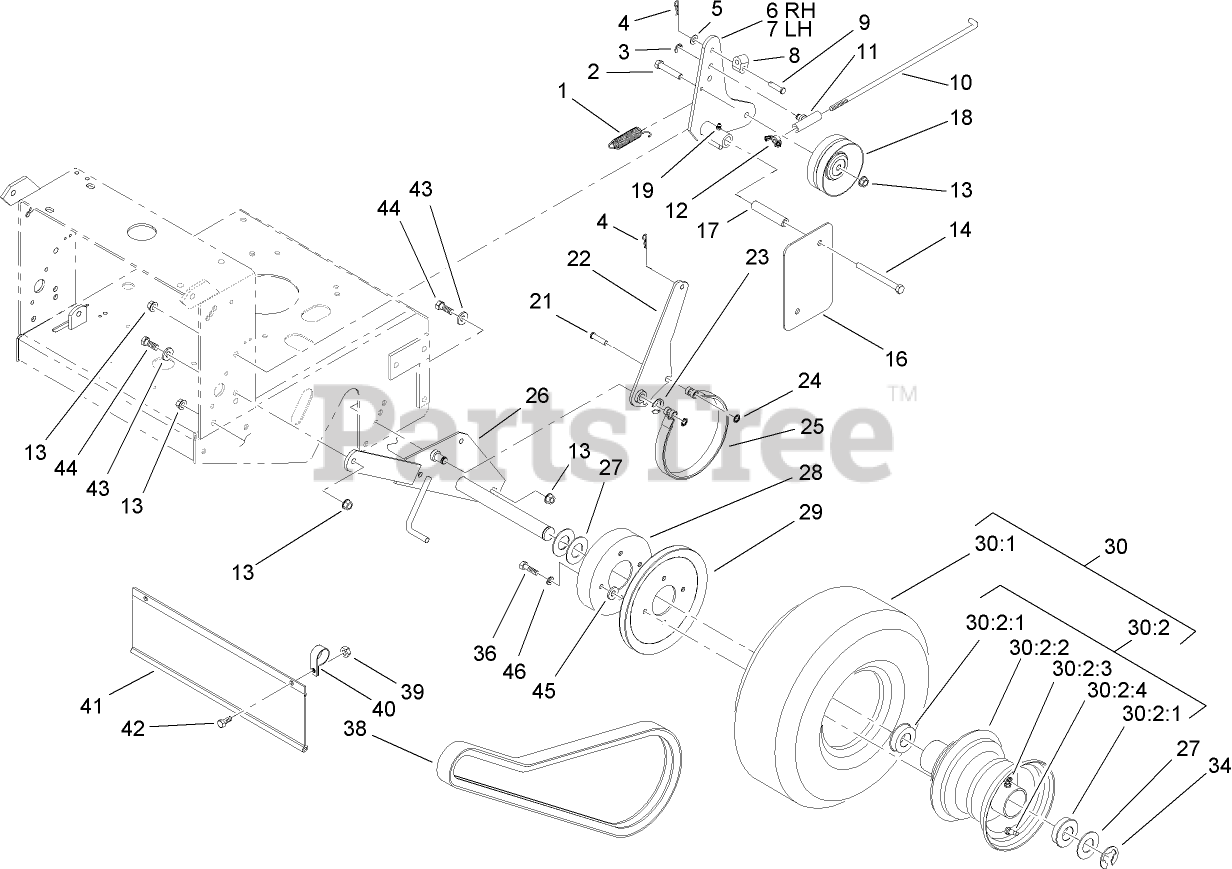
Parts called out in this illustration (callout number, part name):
1	SPRING-EXTENSION
2	SCREW-HH
3	RING-RETAINING
4	PIN-COTTER
5	WASHER-PLAIN
6	ARM-IDLER, RH
7	ARM-IDLER, LH
8	FITTING-ROD
9	PIN-CLEVIS
10	ROD-BRAKE
11	SWIVEL-BRAKE
12	WINGNUT-NYLOCK
13	NUT-HHF, WHIZ
14	SCREW-HH
16	SHIELD-WHEEL, DRIVE
17	SPACER-SHIELD
18	IDLER-DRIVE, WHEEL
19	FITTING-GREASE
21	PIN-CLEVIS
22	ARM-BRAKE
23	RING-RETAINING, EXTERNAL
24	NUT-PUSH
25	BAND-BRAKE
26	AXLE ASM
27	WASHER-SPACER
28	DRUM-BRAKE
29	SHEAVE-WHEEL, DRIVE
30	Wheel AND Tire ASM
30:1	TIRE
30:2	WHEEL AND HUB ASM
30:2:1	BEARING-FLANGED
30:2:2	Rim ASM
30:2:3	Fitting-Grease
30:2:4	Valve Stem and Cap
34	RING-SNAP
36	SCREW-HH
38	BELT-DRIVE, WHEEL
39	NUT-LOCK, NI
40	CLAMP-R
41	SHIELD-TRAILING
42	SCREW-HH
43	WASHER-BELLEVILLE
44	SCREW-HH
45	WASHER
46	WASHER-LOCK
